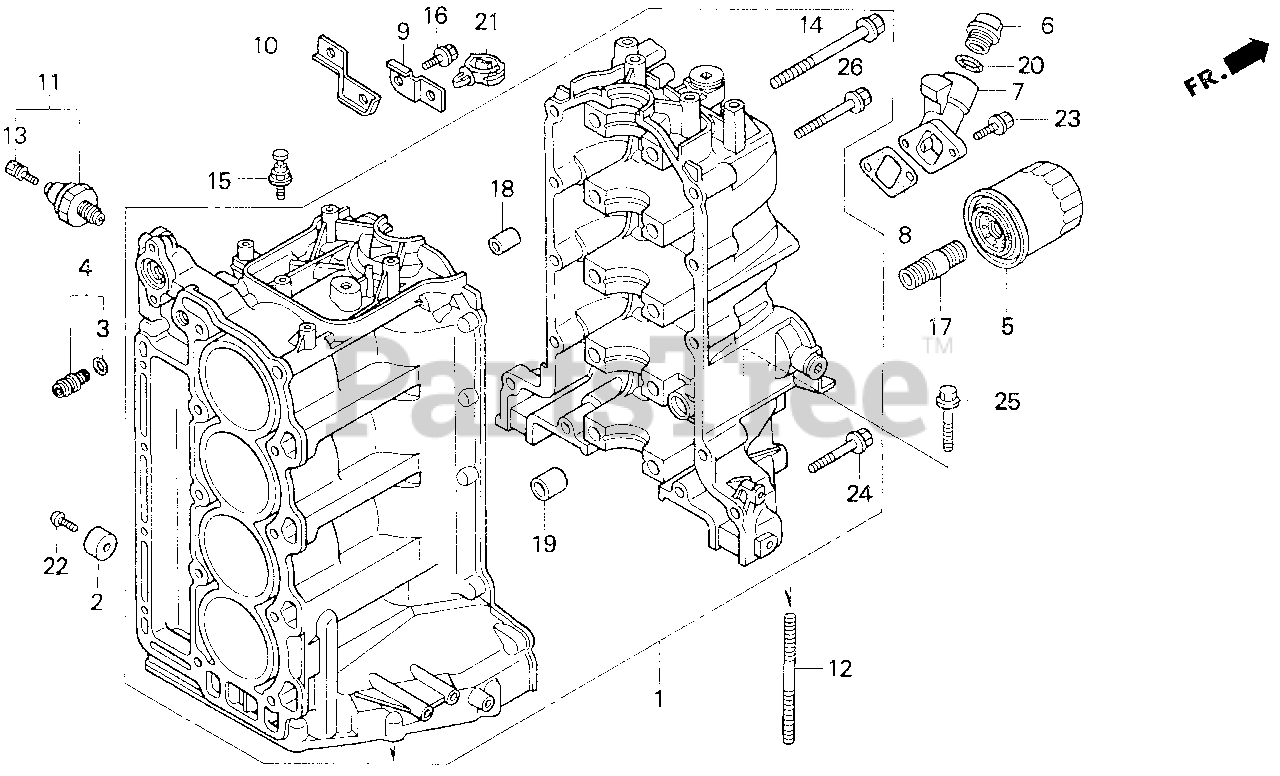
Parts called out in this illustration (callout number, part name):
1	BLOCK ASSY., CYLINDER *NH8* (DARK GRAY)
2	METAL, ANODE
3	O-RING (10.8X2.4) (ARAI)
4	ORIFICE ASSY., OIL PASSAGE
5	FILTER, OIL (FILTECH TOYO ROKI) (SOLD INDIVIDUALLY)
5	FILTER, OIL (SOLD INDIVIDUALLY)
7	EXTENSION, OIL FILLER *NH8* (DARK GRAY)
8	GASKET, EXTENSION OIL FILLER (NON-ASBESTOS)
9	BRACKET, HARNESS CLIP
10	CLAMP C, ENGINE WIRE HARNESS
11	SWITCH, OIL PRESSURE
12	BOLT, STUD (10X125)
13	SCREW-WASHER (4X8)
14	BOLT-WASHER (10X112)
15	BOLT, TIMING BELT ADJUST SPRING
16	BOLT, FLANGE (6X14)
17	HOLDER, OIL FILTER
18	PIN, DOWEL (12X18)
19	PIN, DOWEL (18X22)
20	O-RING (26X2.7)
21	CLIP, WIRE HARNESS *NH1L* (BLACK)
22	SCREW, PAN (6X18)
23	BOLT, FLANGE (6X22)
24	BOLT, FLANGE (8X35)
25	BOLT, FLANGE (8X40)
26	BOLT, FLANGE (8X50)
